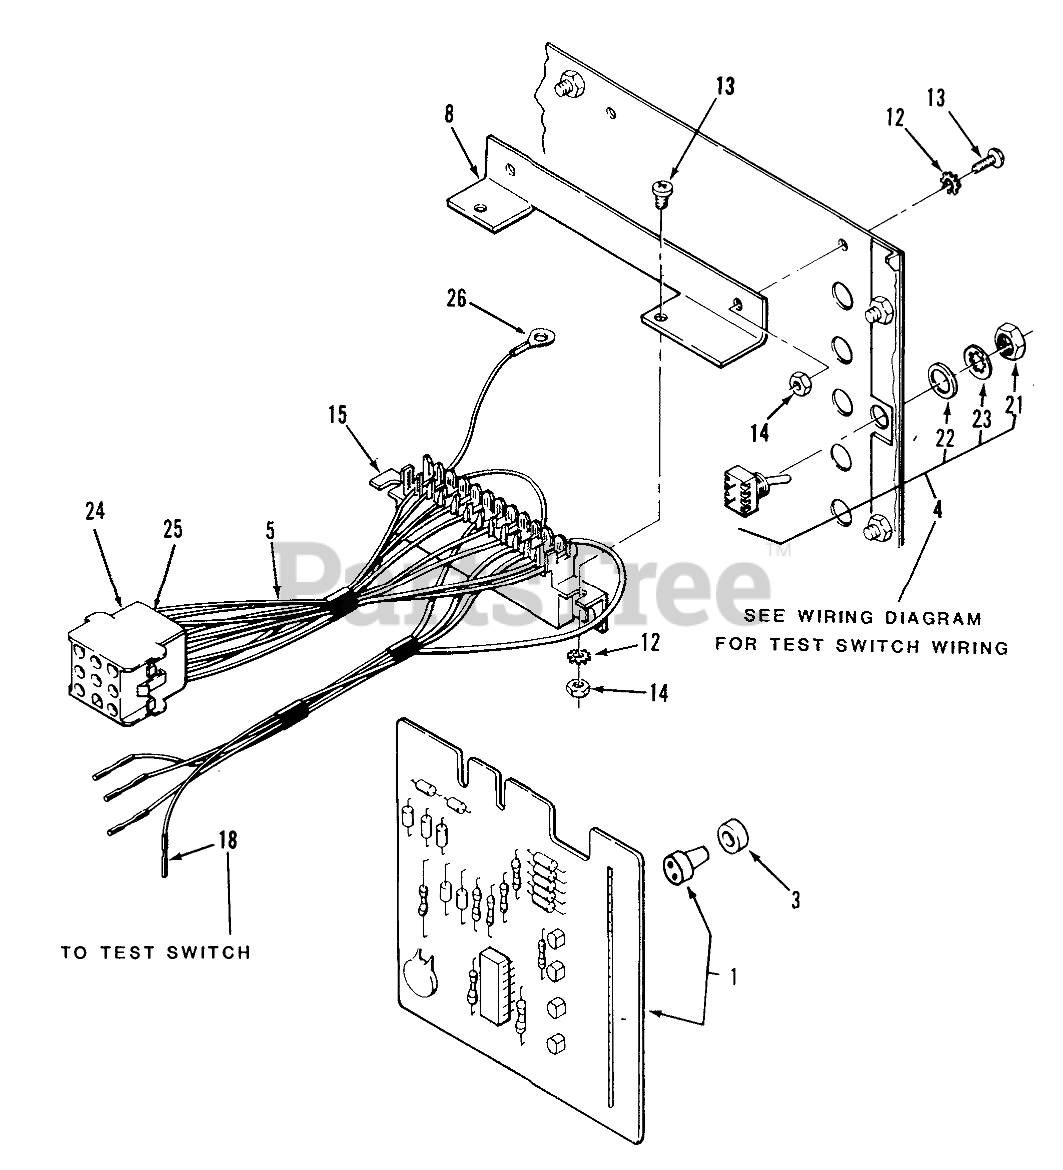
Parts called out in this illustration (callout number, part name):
1	Board-Pc
3	ASSY LENS & BUSHING
4	SWITCH TOGGLE
5	P.C. BOARD HARNESS
8	BRACKET
12	Washer-Lock
13	SCREW
14	Nut
15	Molex Connector (Part of 6)
18	062 X 031 TAB RECEPT
21	NUT F/W 116796
22	RING LOCKING
23	Washer
24	9-CIRCUIT CAP
25	TERMINAL - SOCKET
26	No. 6 Ring Terminal
